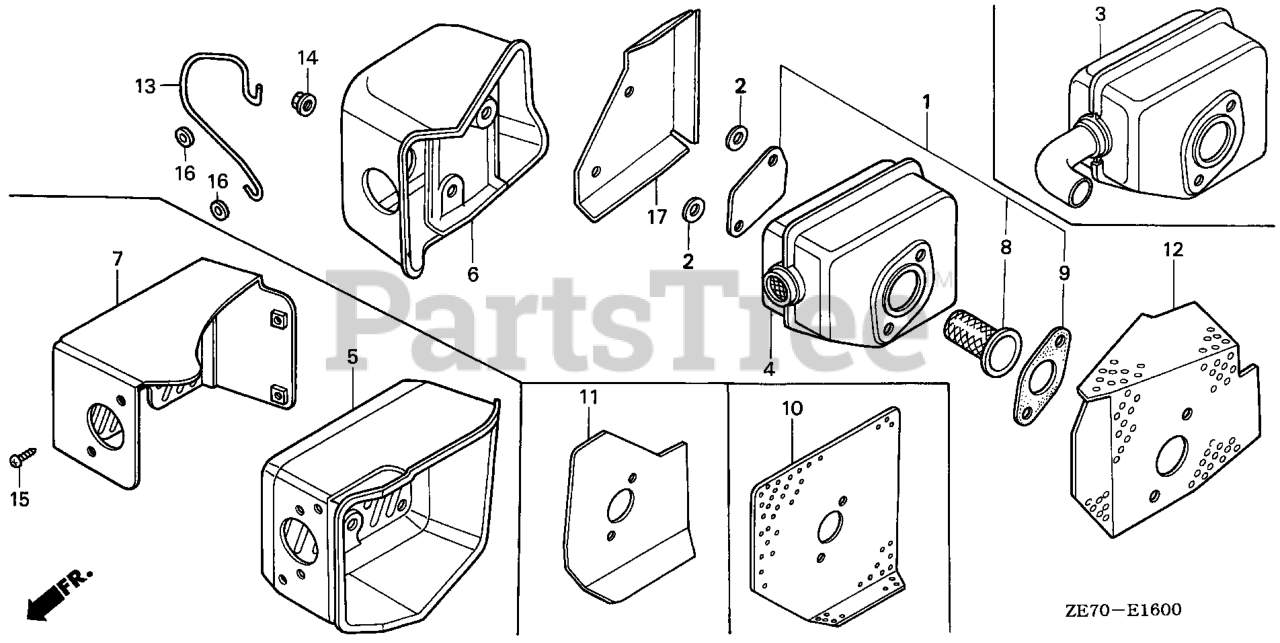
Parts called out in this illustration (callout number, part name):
1	ARRESTER KIT, SPARK
4	MUFFLER
6	PROTECTOR, MUFFLER
8	ARRESTER KIT, SPARK
9	GASKET, MUFFLER
12	GASKET, MUFFLER
14	NUT, SELF-LOCK (6MM)
